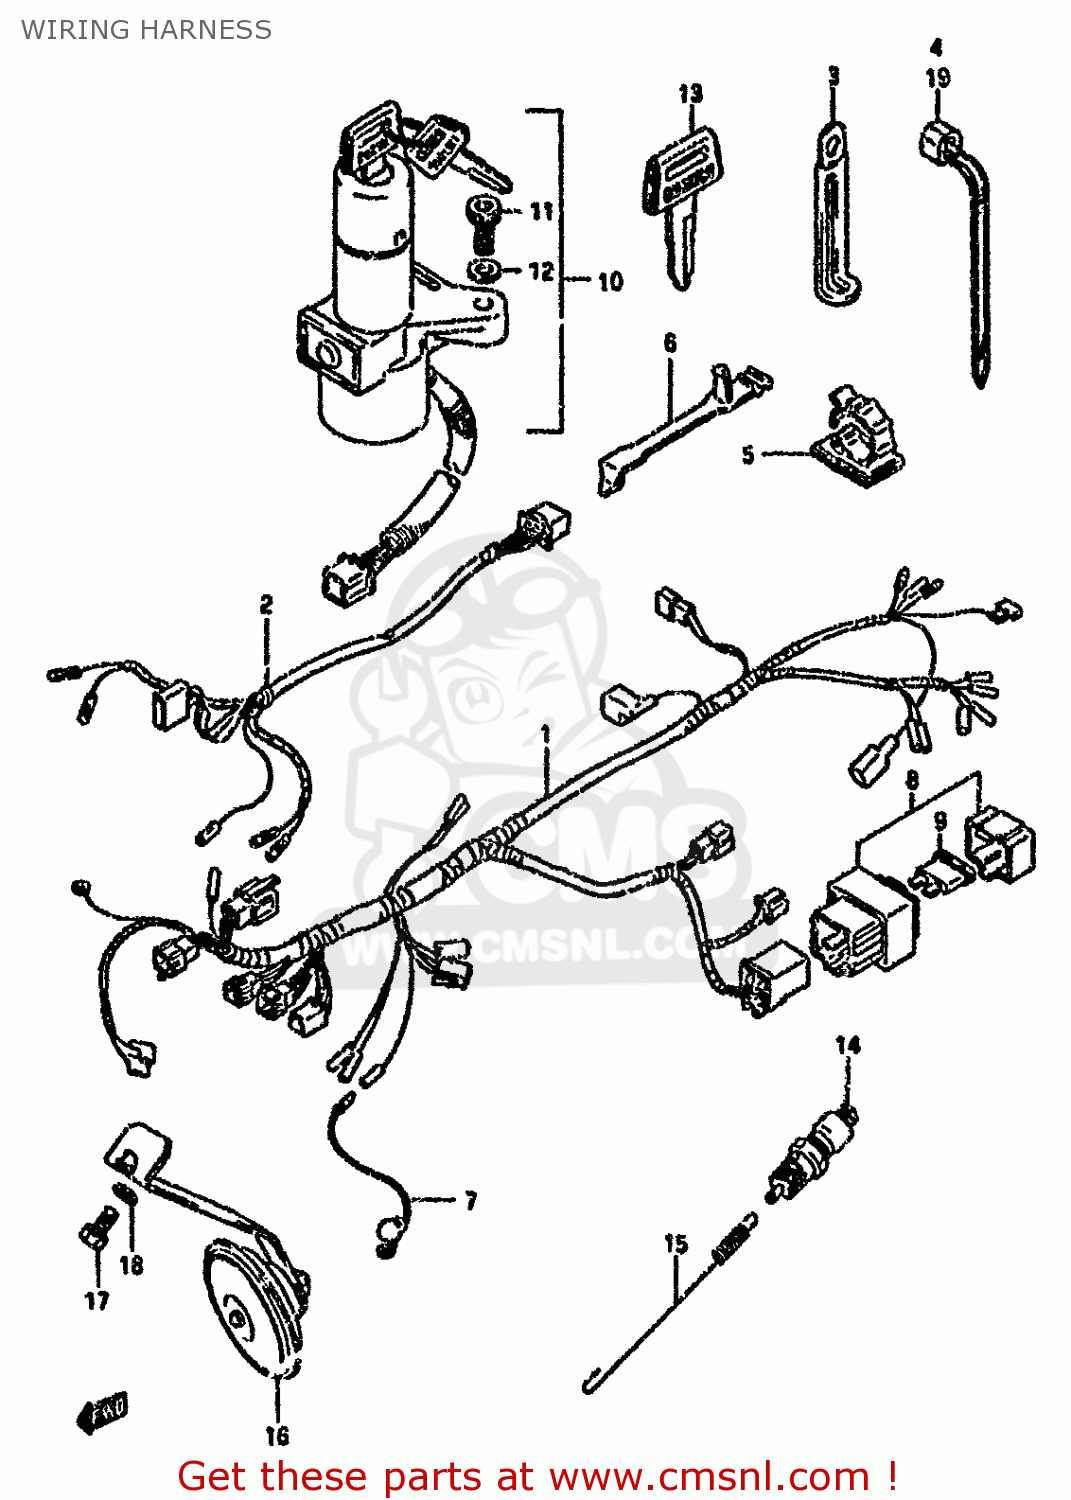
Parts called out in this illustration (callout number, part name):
1	HARNESS,WIRING NO.1
2	HARNESS,WIRING NO.2
3	CLAMP
4	CLAMP L:165
5	CLAMP
6	CLAMP(L:55)
7	WIRE,WATER TEMPERATURE GAUGE
8	BOX ASSY,FUSE
9	FUSE(15A)
10	SWITCH ASSY,IGNITION
11	BOLT
12	WASHER,LOCK
13	KEY,BLANK
14	SWITCH ASSY,STOP LAMP
15	SPRING
16	HORN ASSY
17	BOLT
18	WASHER,LOCK
19	CLAMP(L:235)
